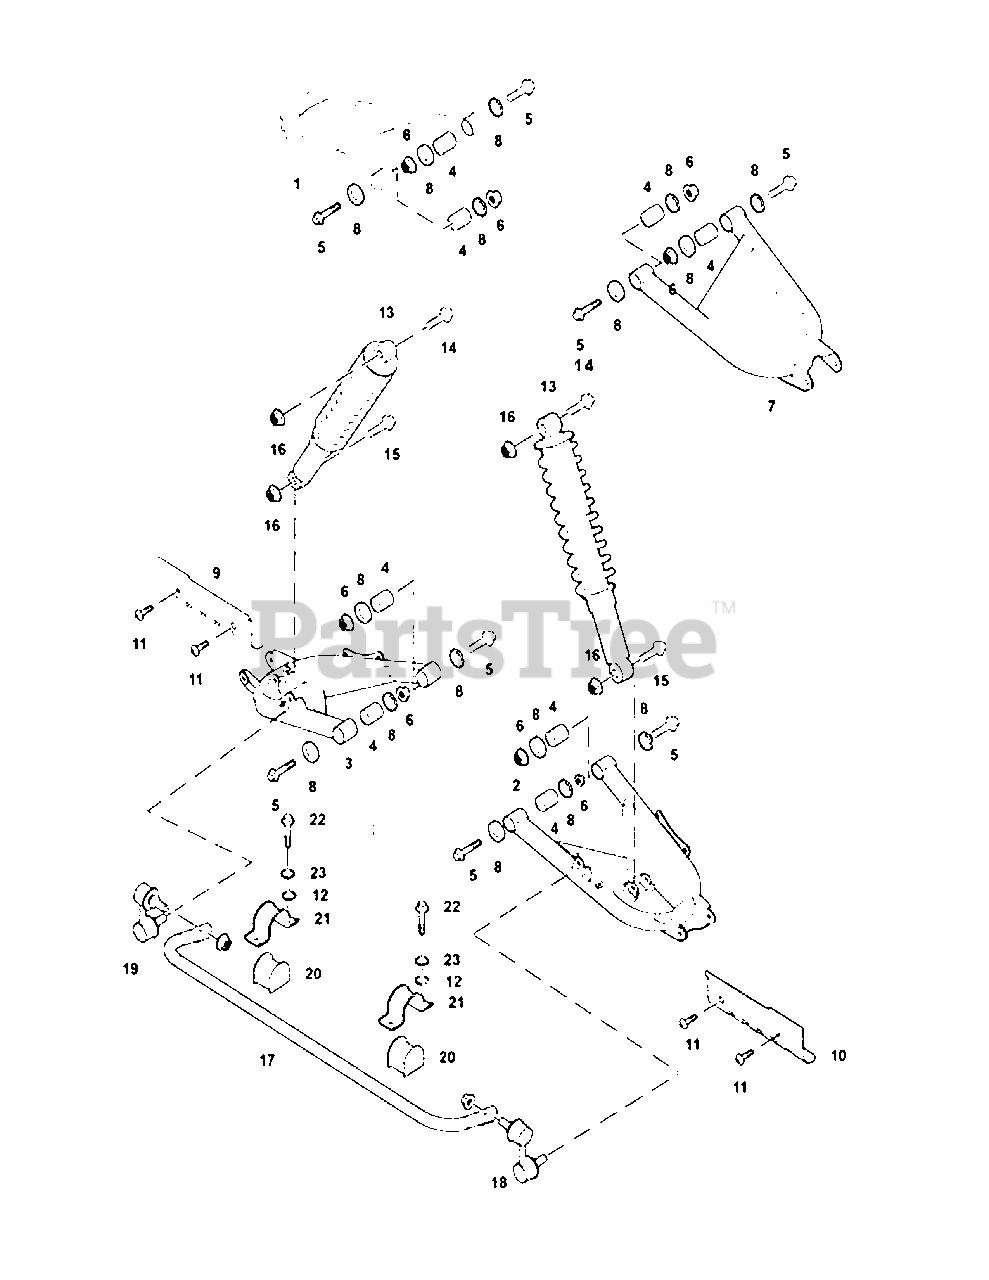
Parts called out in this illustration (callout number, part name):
1	Rear Right Upper Swing Arm
2	Rear Left Lower Swing Arm
3	Rear Right Lower Swing Arm
4	Bushing 10×23×50
5	Bolt M10×1.25×78
6	Hexagon flange nut M10×1.25
7	Rear Left Upper Swing Arm
8	Nylon Bushing
9	Protective Board, Rear Right Lower Swing Arm
10	Protective Board, Rear Left Lower Swing Arm
11	Cross large plate head screw M6×16
12	Cushion 8.4×16×1.6
13	Rear Shock Absorber
14	Hexagon Flange Bolt M12×1.25×70
15	Bolt M12×1.25×60
16	Hexagon Flange Nut M12×1.25
17	Rear Anti-Roll Bar
18	Left Tie-Rod, Anti-Roll Bar
19	Right Tie-Rod, Anti-Roll Bar
20	U-type Rubber bush III
21	Press Block, Rear Anti-Roll Bar
22	Hexagon Flange Bolt M8×22
23	Spring Washer -8
